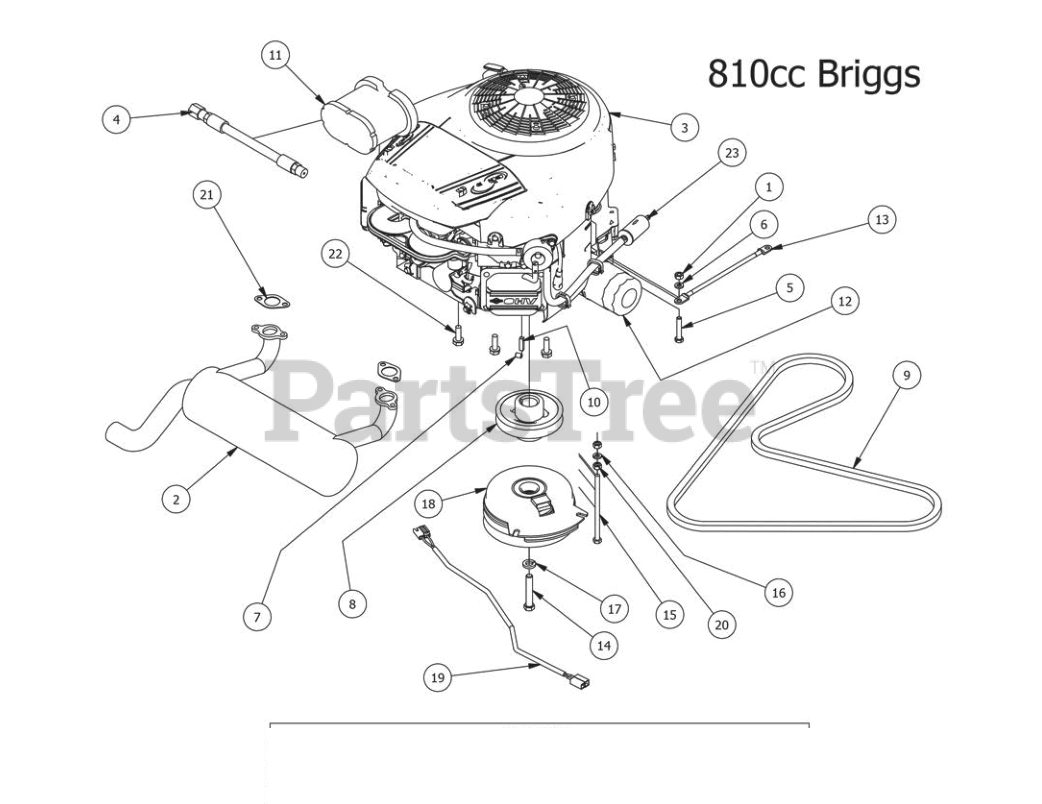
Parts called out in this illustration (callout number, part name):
2	Exhaust-Stand On
3	810cc Briggs Engine W/Cyclonic Filter
4	Oil drain Hose
5	5/16" x 1 3/4" Hex Bolt
6	5/16" Lock Washer
7	3/8" Set Screw
8	4 3/4 Motor Pulley
10	1/4" x 1" Key
11	Briggs Air Filter
12	Oil Filter
13	Starter to chassis cable
14	7/16" x 2 1/2" Hex Bolt
15	5/16-18 x 5-1/2 GR 5 Hex Bolt
16	5/16" Lock Washer
17	7/16" Lock Washer
18	Clutch Assembly
19	Clutch Pigtail
21	Exhaust gasket
22	3/8 x 1 1/8 bolt
23	Universal Inline Fuel Filter
